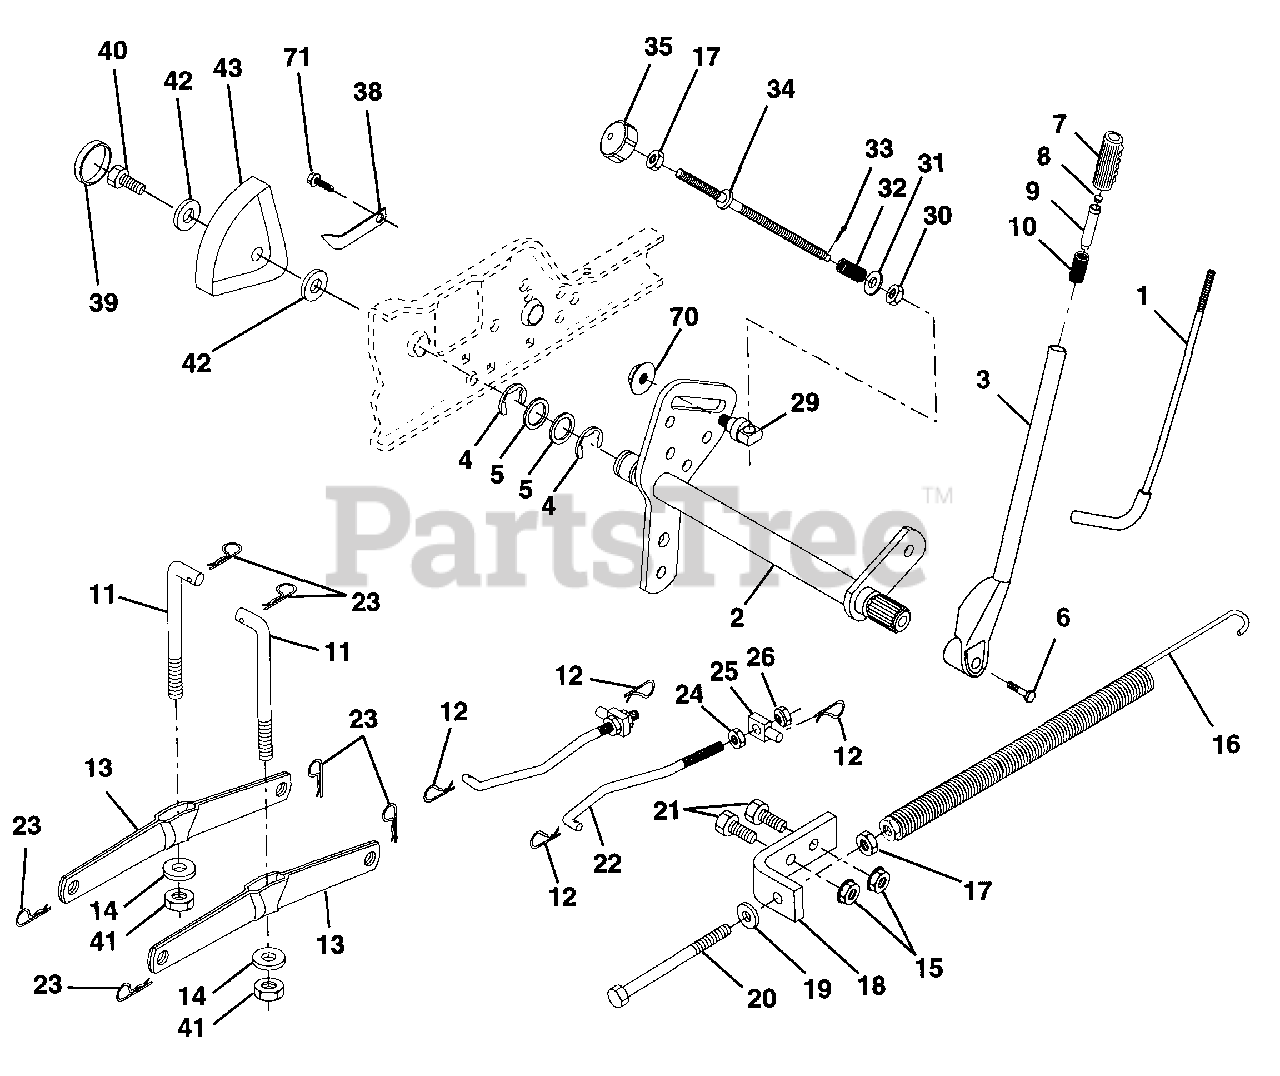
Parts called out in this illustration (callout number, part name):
1	Rod Asm., Lever
2	Shaft Asm., Lift Vgt
3	Lever Asm., Lift Rh
4	E-Ring Truarc #5133-87
5	Washer 29/32 x 1-1/4 x 16 Ga.
6	Bolt, Fin Hex 3/8-16 x 1-1/2
7	Grip, Handle Fluted
8	Button, Plunger
9	Plunger, Lever Lift
10	Spring 2-1/8"
11	Link Lift
12	Retainer, Spring
13	Arm, Suspension Vgt
14	Bearing
15	Nut, Crownlock 3/8-16 Unc
16	Spring Asm., Assist Lift
17	Nut, Hex Jam 3/8-16 Unc
18	Bracket, Spring Assist
19	Washer 13/32 x 13/16 x 16 Ga.
20	Bolt, Adjust Spring Assist
21	Bolt, Fin Hex 3/8-16 x 1
22	Link, Front
23	Retainer, Spring
24	Nut, Jam Hex 1/2-13 Unc
25	Trunnion
26	Nut, Lock W/Wsh 1/2-13 Unc
29	Trunnion, Infin Height
30	Nut, Special
31	Washer 13/32 x 5/8 x 16 Ga.
32	Spring, Compression Inf Hgt
33	Pin, Cotter 3/32 x 1/2
34	Rod, Adj Lift
35	Knob, Inf 3/8-16 Unc
36	Screw, Thdrol 3/8-16 x 3/4
37	Washer, Nylon
38	Pointer, Pnt Height Indicator
39	Plug, Hole
40	Screw Thdrol 5/16-18 x 3/4
41	Nut, Crownlock 3/8-24
42	Washer 11/32 x 1-1/2 x 10 Ga.
43	Scale, Indicator Height
70	Nut Hex Flange Lock
